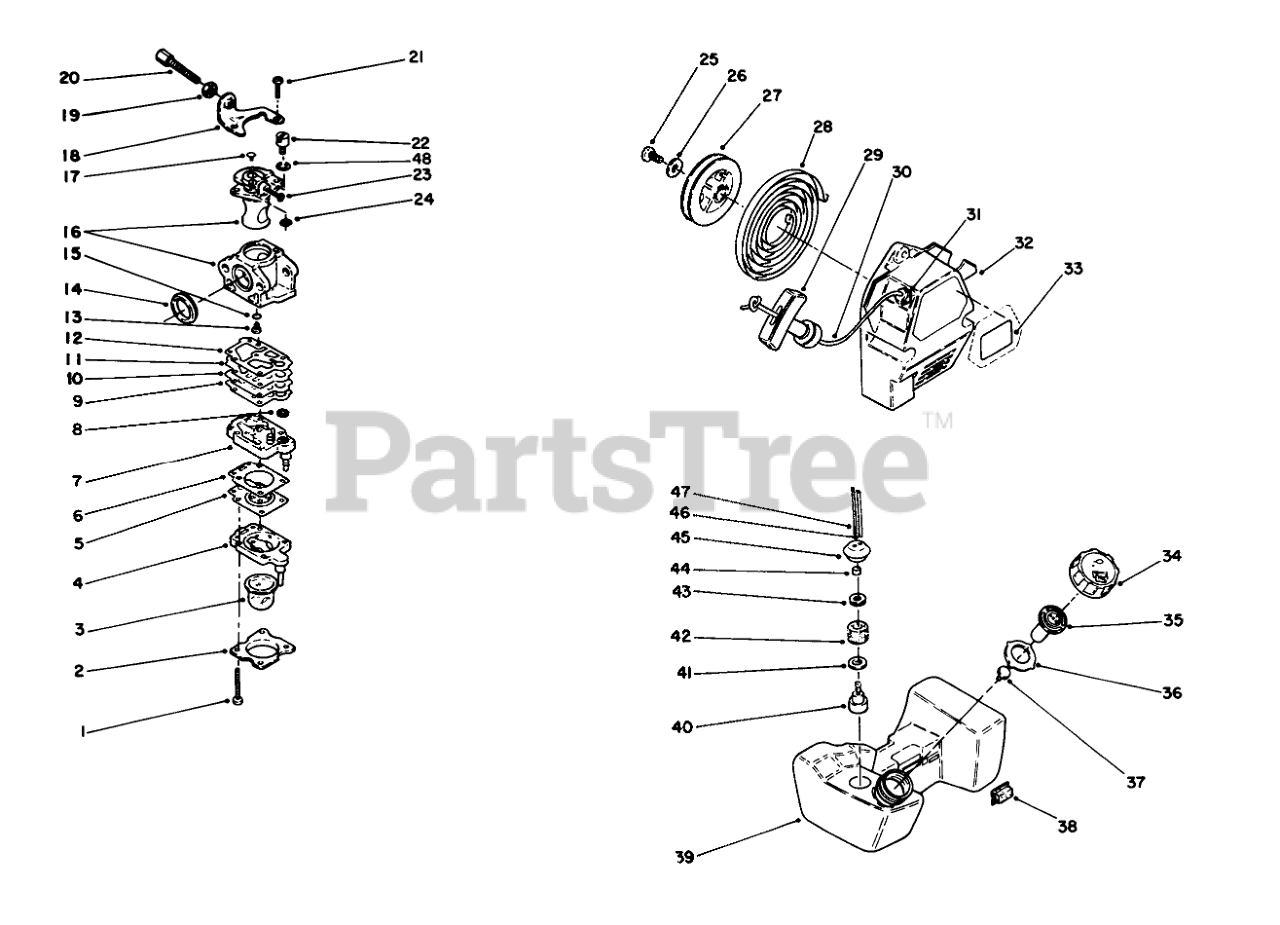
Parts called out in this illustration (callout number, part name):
1	SCREW
2	Cover-Primer
3	PRIMER PUMP
4	PRIMER BODY
5	DIAPHRAGM
6	DIAPHRAGM GASKET
7	Body Assembly (Incl. Ref. #8)
8	SCREEN
9	PUMP GASKET
10	Plate
11	DIAPHRAGM
12	DIAPHRAM GASKET
13	MAIN JET
14	RUBBER CARB GASKET
15	MAIN JET O-RING
16	Body-Carburetor (Ref.)
18	BRACKET
19	LOCKNUT
20	ADJUSTING SCREW
21	SCREW
22	Holder-Wire
23	THROTTLE VALVE
25	SCREW
26	WASHER
28	SPRING
29	Knob-Starter
30	Rope-Recoil
31	GUIDE
32	RECOIL CASE
33	Decal-Toro
34	FUEL TANK CAP
35	BREATHER VALVE
36	PACKING
39	Tank Assembly-Fuel (Incl. Ref. #34-37 & 40-47)
40	Weight-Filter
42	Filter-Fuel
43	Washer-Seal
44	COLLAR
45	FUEL TANK GROMMET
46	TUBE, FUEL
47	RETURN FUEL HOSE
48	WASHER
